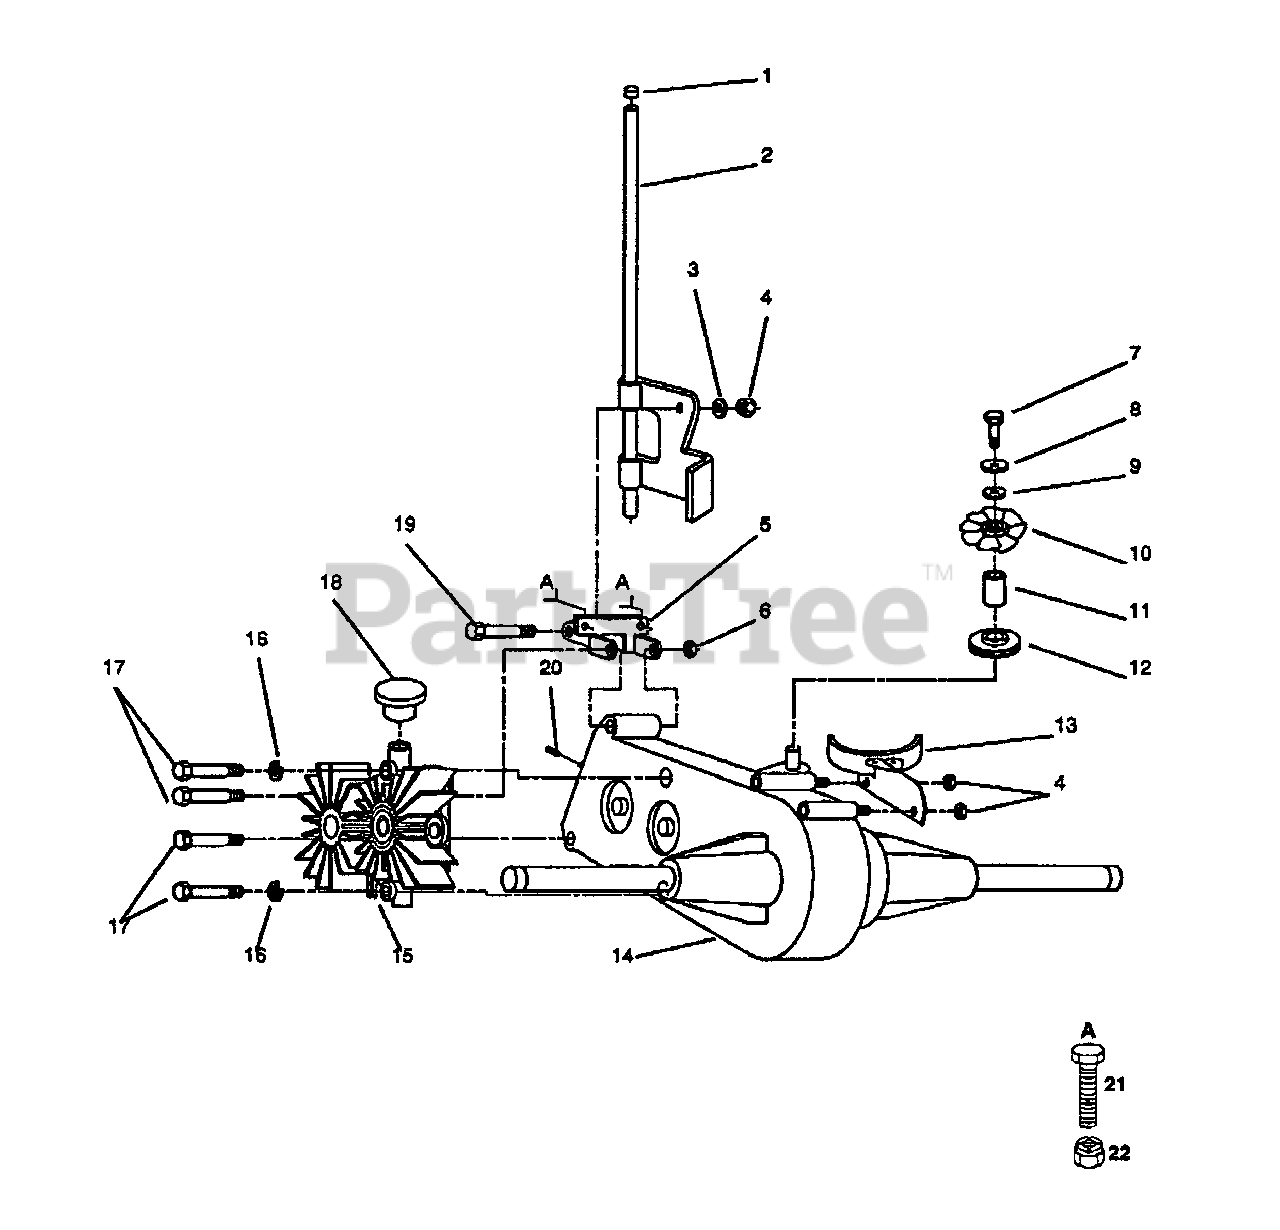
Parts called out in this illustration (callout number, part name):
1	Cap, Plunger
2	Rod, Free Wheel Control Assembly
3	Washer, Nylon
4	Nut, Crownlock 1/4-20 UNC
5	Bracket, Painted, Mounting, Differential
6	Nut, Crownlock 5/16-18
7	Bolt, Hex 1/4-20 UNC x 3/4
8	Washer
9	Washer 9/32 x 1-1/4 x 18 Gauge
10	Fan, Hydro, 8"
11	Standoff, Fan, Hydro
12	Pulley, Transaxle
13	Guard Assembly, Belt
14	Differential Assembly
15	Pump Assembly
16	Washer Lock
17	Bolt, Hex Fin 5/16-18 UNC x 4 1/2
18	Reservoir, Pump
19	Bolt, Shoulder 1/4-20 UNC
20	Spring, Compression
21	Bolt, Hex 3/8-16 x 3/4
22	Nut, Crownlock 3/8-16 UNC
